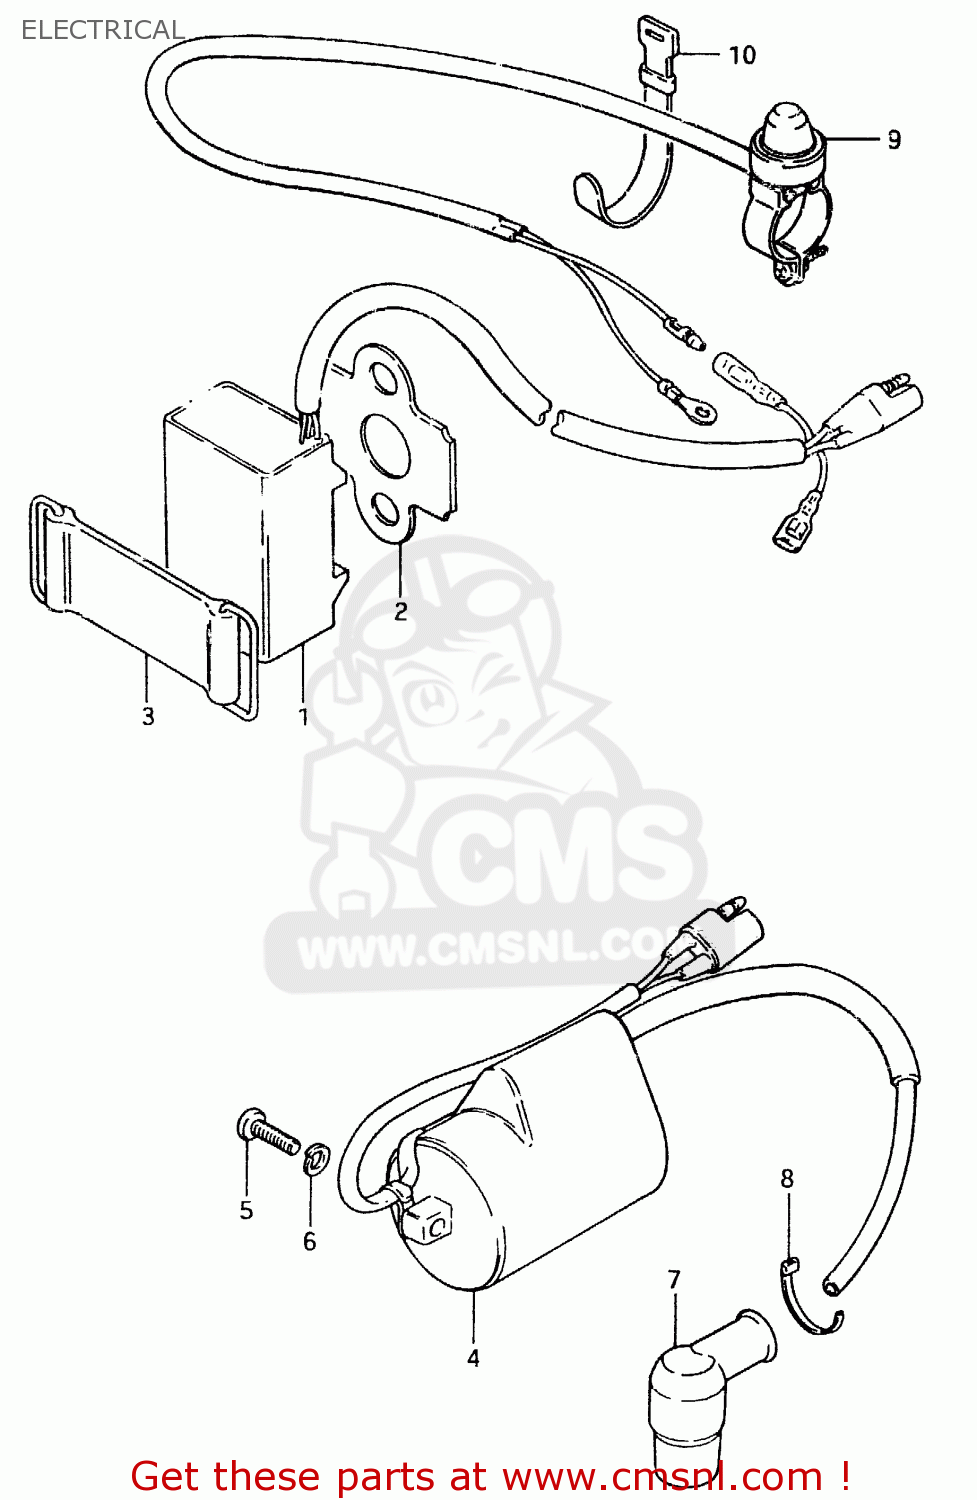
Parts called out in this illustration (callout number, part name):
1	CDI UNIT
2	PROTECTOR,CDI UNIT
3	BAND
4	COIL ASSY,IGNITION
5	SCREW 5X20
6	LOCK WASHER
7	CAP, SPARK PLUG
8	CLAMP
9	SWITCH ASSEMBLY
10	CLAMP(L:120)
